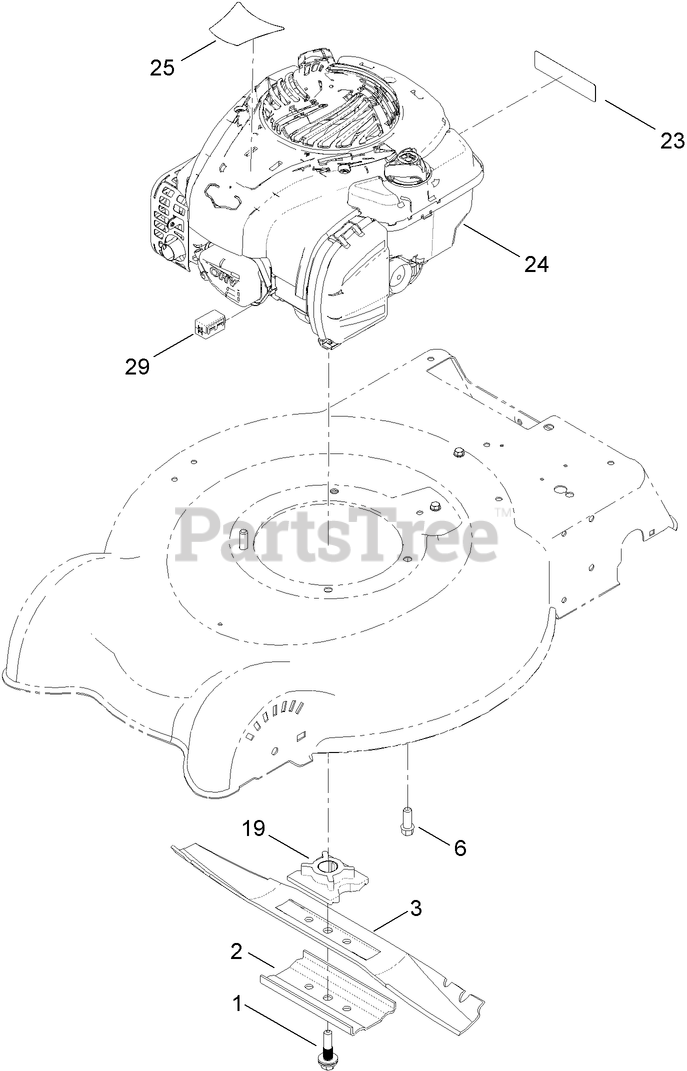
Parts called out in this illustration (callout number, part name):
1	BOLT-BLADE
2	SUPPORT-BLADE
6	SCREW-TAPTITE
19	RETAINER-BLADE
23	DECAL-ARRESTER, SPARK
25	DECAL-ENGINE
29	FERRITE-CLAMP
